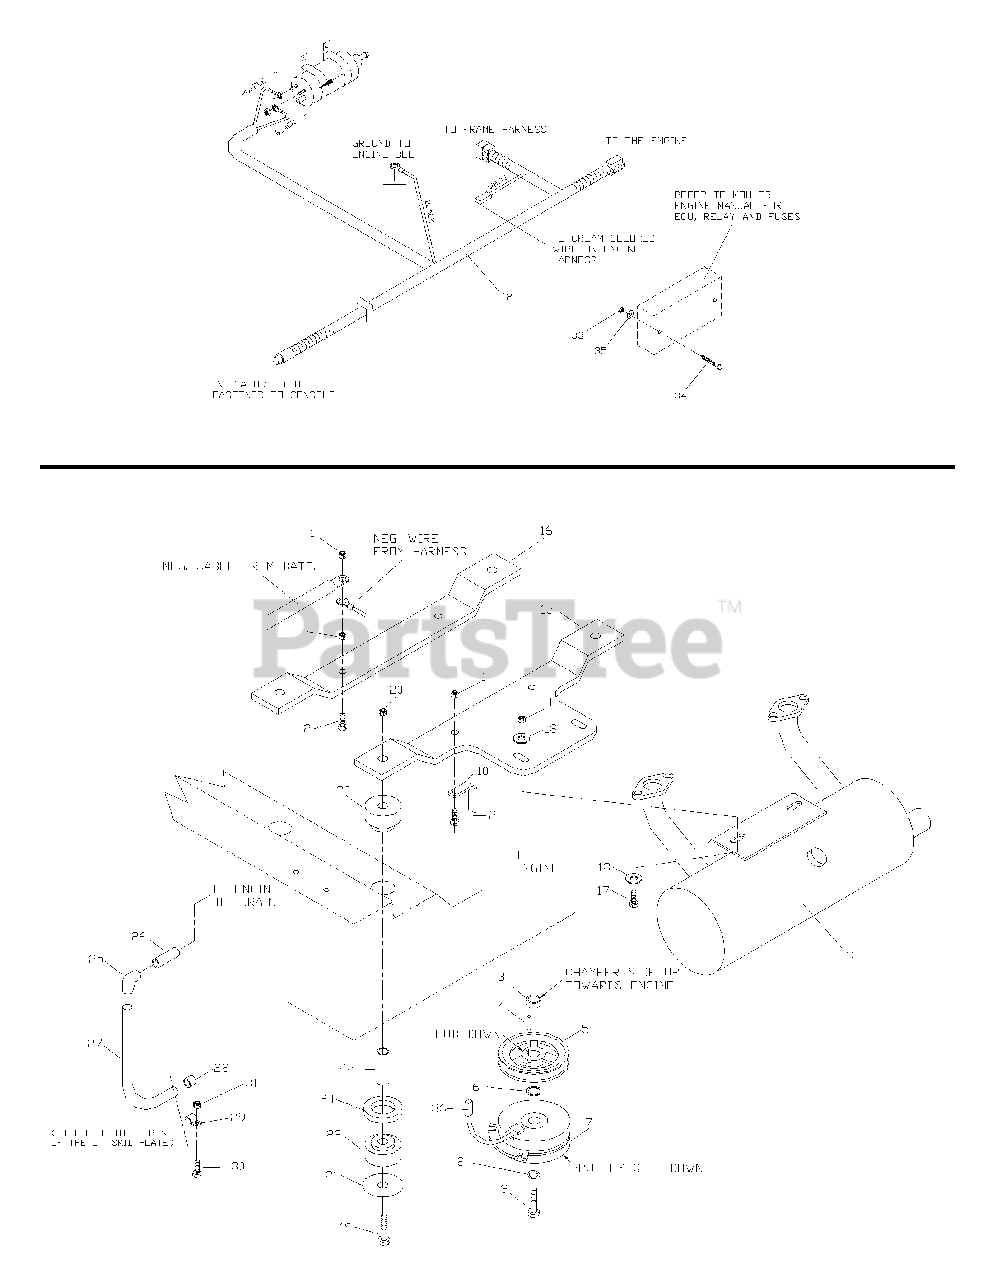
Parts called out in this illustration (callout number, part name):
1	NUT 5/16C CTR. LOCK
2	HCS 5/16C X 1.75
4	KEY 1/4SQ. X 1.0
7	ELECTRIC CLUTCH 200 lb.
8	7/16 LOCKWASHER
9	HCS 7/16F X 2.5
10	CLUTCH TIE DOWN
12	EFI HARNESS
15	ENGINE MOUNT
16	ENGINE MOUNT
17	HCS 5/16C X 1
18	5/16 FLAT WASHER
19	HCS 1/2C X 3.25
20	NUT 1/2C NYLOC
21	ISOLATOR WASHER
24	ISOLATOR SPACER
26	PIPE 3/8 NPT.
27	OIL DRAIN HOSE
28	OIL DRAIN CAP
30	HCS 1/4C X 3/4
31	NUT 1/4C CTR. LOCK
32	SELF TAPPING SCREW
33	NUT #10-24
34	#10-24 X 2
35	WASHER #10
36	CLUTCH HARNESS
